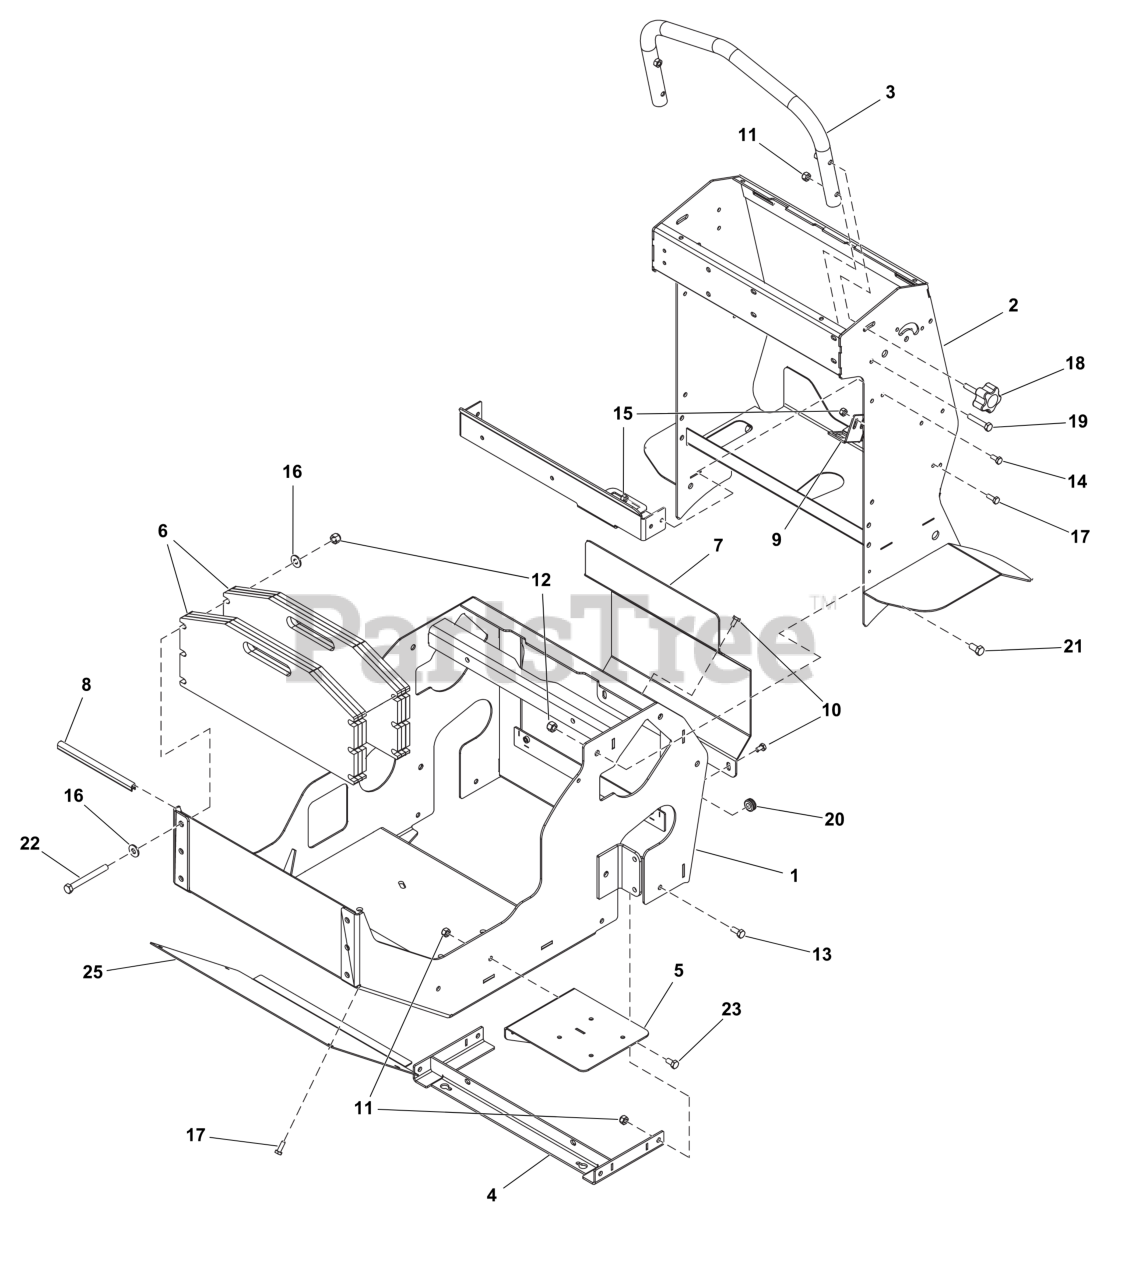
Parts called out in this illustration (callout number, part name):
1	WELD, MAIN FRAME LOWER
2	WELD, HAND CONTROLS
3	WELD, STATIONARY HANDLEBAR
4	WELD, LOWER MOUNT TRANSAXLE
5	WELD, BATTERY SUPPORT PLATE
6	WELD, PLATE COUNTER WEIGHT
7	PLATE, BACK W/ EXTENSION (SANDED)
8	TRIM FOR CONSOLE HEAVY DUTY, 7 INCH
9	PLATE, PARKING BRAKE SWITCH
10	SCR-CAP, HEX .250"-20 X .500" SS188
13	SCR-CAP, HEX .3125"-18 X .750" SS188
14	SCR-CAP, HEX .250"-20 X .625" SS188
16	WSHR-SS, FLT .375"X.875"X.083" USS
17	SCR-CAP, HEX .250"-20 X .750" SS188
18	KNOB, STATIONARY CONTROL BAR
19	SCR-CAP, HEX .3125"-18 X 1.750" SS188
20	GROMMET, 0.375" I.D., FIT 0.500" HOLE
21	SCR-CAP, HEX .375"-16 X .750" SS188
22	SCR-CAP, HEX .375"-16 X 3.500" SS188
23	SCR-CAP, HEX .3125"-18 X .625" SS188
24	BRACKET, EXPANSION TANK MOUNT
25	PLATE, FRONT ENGINE COVER
